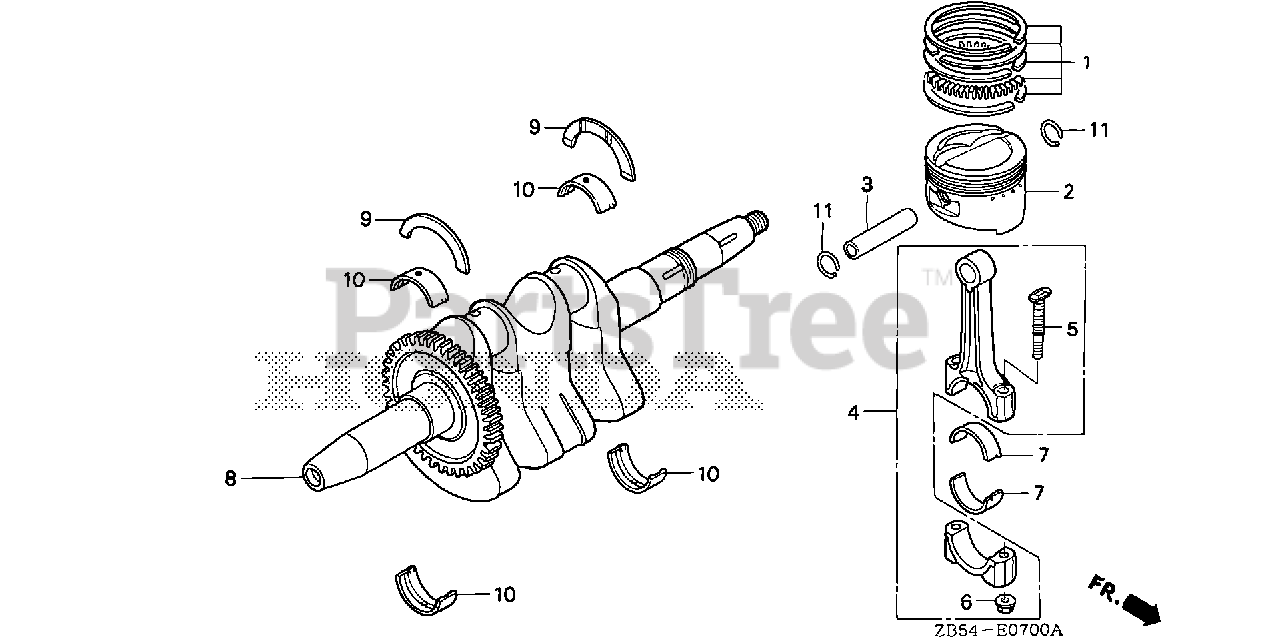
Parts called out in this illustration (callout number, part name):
1	RING SET, PISTON (STD)
1	RING SET, PISTON (OS 0.25)
1	RING SET, PISTON (0.25) (TEIKOKU)
1	RING SET, PISTON (0.50) (RIKEN)
1	RING SET, PISTON (OS 0.50)
2	PISTON (STD)
2	PISTON (OS 0.25)
2	PISTON (OS 0.50)
3	PIN, PISTON
4	ROD ASSY., CONNECTING
5	BOLT, CONNECTING ROD
6	NUT, CONNECTING ROD
7	BEARING A, CONNECTING ROD (Honda Code 0282053). (BLACK)
7	BEARING B, CONNECTING ROD (Honda Code 0282251). (BROWN)
7	BEARING C, CONNECTING ROD (Honda Code 0282285). (GREEN)
7	BEARING D, CONNECTING ROD (Honda Code 0282293). (YELLOW)
7	BEARING E, CONNECTING ROD (Honda Code 0282301). (RED)
8	CRANKSHAFT (EV-TYPE)
9	BEARING, CRANKSHAFT THRUST
10	BEARING, CRANKSHAFT (1) (Honda Code 1278183). (BLACK)
10	BEARING, CRANKSHAFT (2) (Honda Code 1278191). (BROWN)
10	BEARING, CRANKSHAFT (3) (Honda Code 1278217). (GREEN)
10	BEARING, CRANKSHAFT (4) (Honda Code 1278225). (YELLOW)
10	BEARING, CRANKSHAFT (5) (RED)
11	CLIP, PISTON PIN (14MM)
